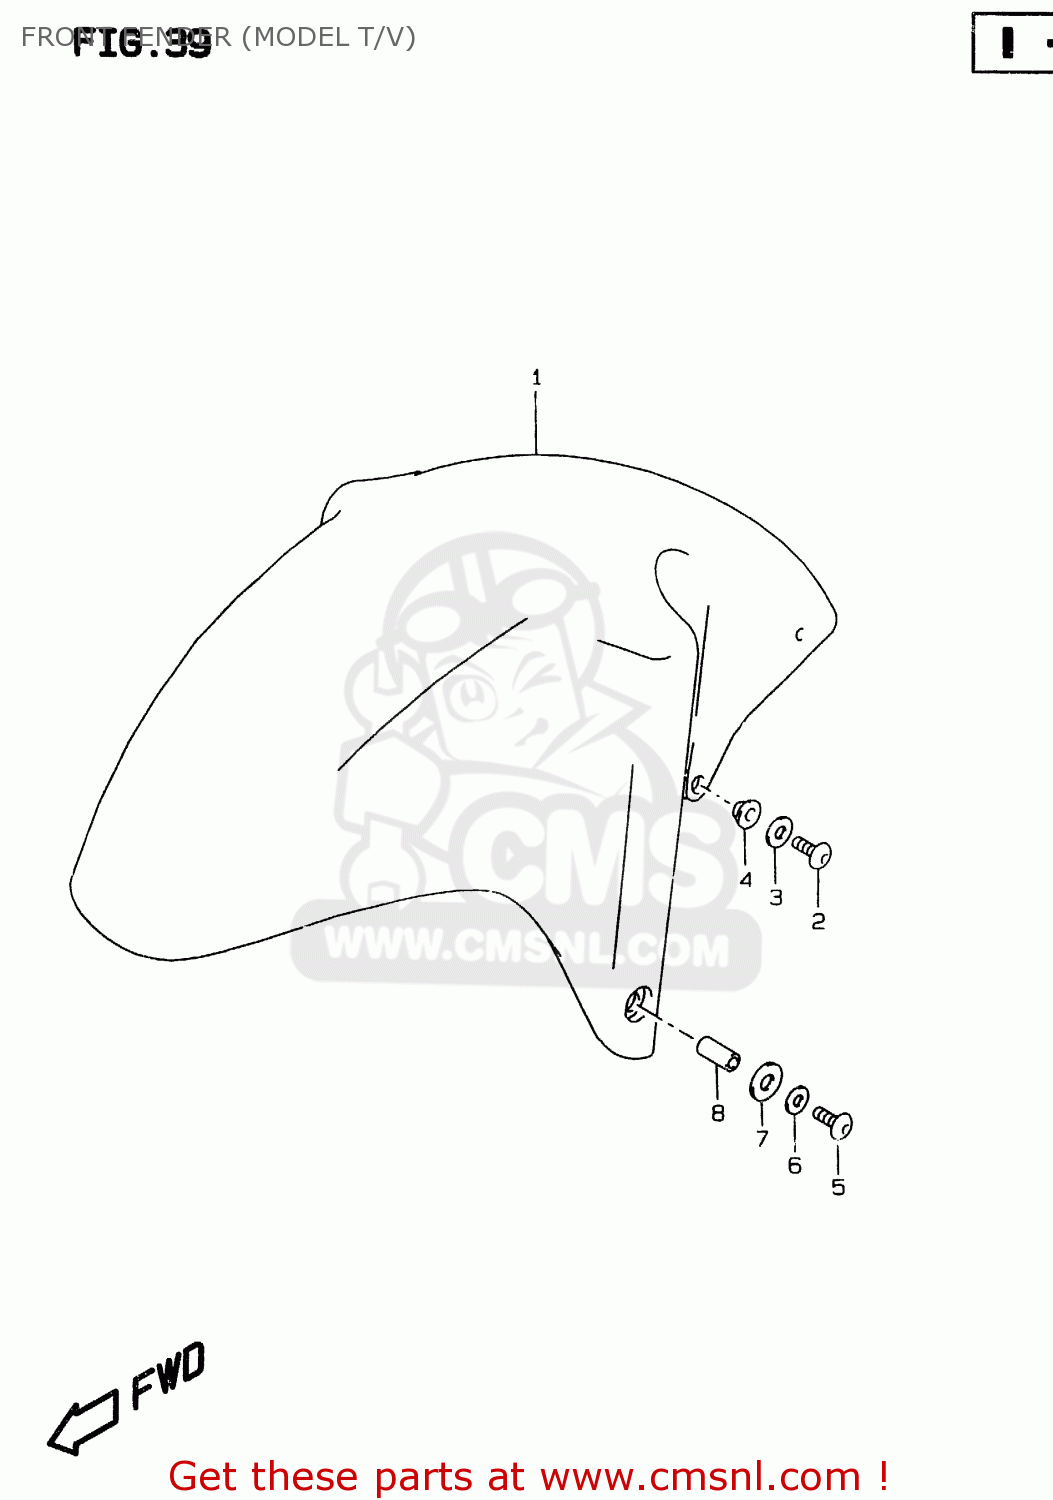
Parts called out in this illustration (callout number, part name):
1	FENDER COMP,FRONT
2	SCREW(6X16)
3	WASHER(6.5X16X1.2)
4	WASHER(6.3X16X1.5)
5	SCREW(6X16)
6	WASHER(6.5X16X1.2)
7	WASHER,FR FENDER FR NO.2
8	SPACER(6.5X9X6.7)
